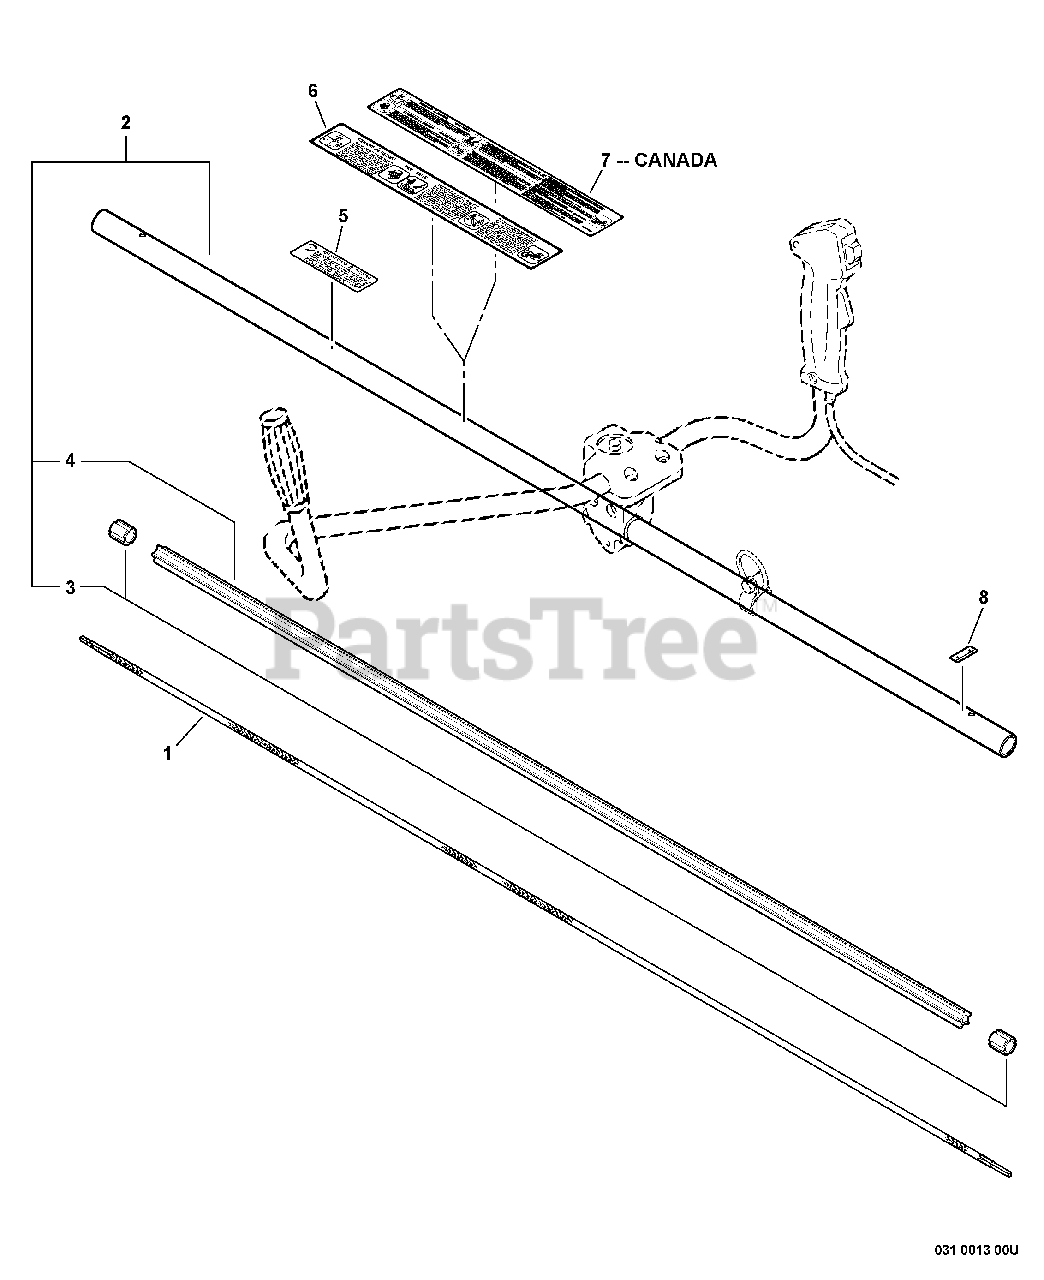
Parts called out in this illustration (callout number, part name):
1	DRIVESHAFT - FLEXIBLE L= 1522
2	MAIN PIPE ASSY
4	LINER, FLEXIBLE 21.6×1420
5	LABEL, CAUTION
6	LABEL, CAUTION
7	LABEL, CAUTION
8	LABEL - ALIGNMENT
